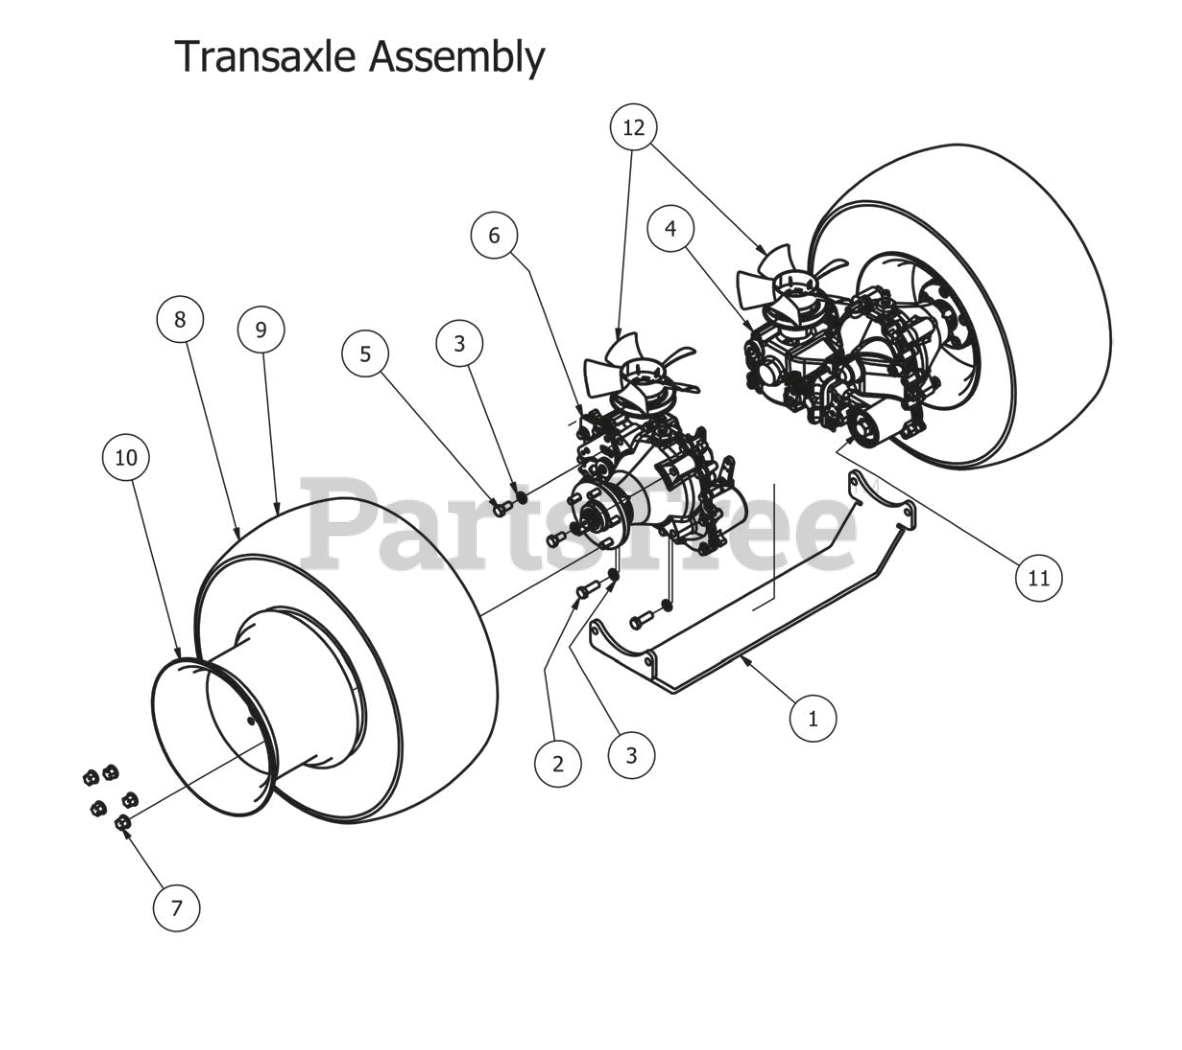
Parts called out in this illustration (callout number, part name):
1	Outlaw Transaxle Cross Brace
2	1/2" x 1 1/2" Hex Bolt
3	1/2" Lock Washer
4	ZT-5400- Right
5	1/2" x 1" Hex Bolt
6	ZT-5400 Left
7	Acorn Lug Nut
8	24 x 12.00-10 Tire and Wheel assembly
9	24 x 12.00 - 10 outlaw Tire
10	10" Wheel For Outlaw
11	Hydro Filter for Outlaw
12	Fan/Pulley Kit for Outlaw
